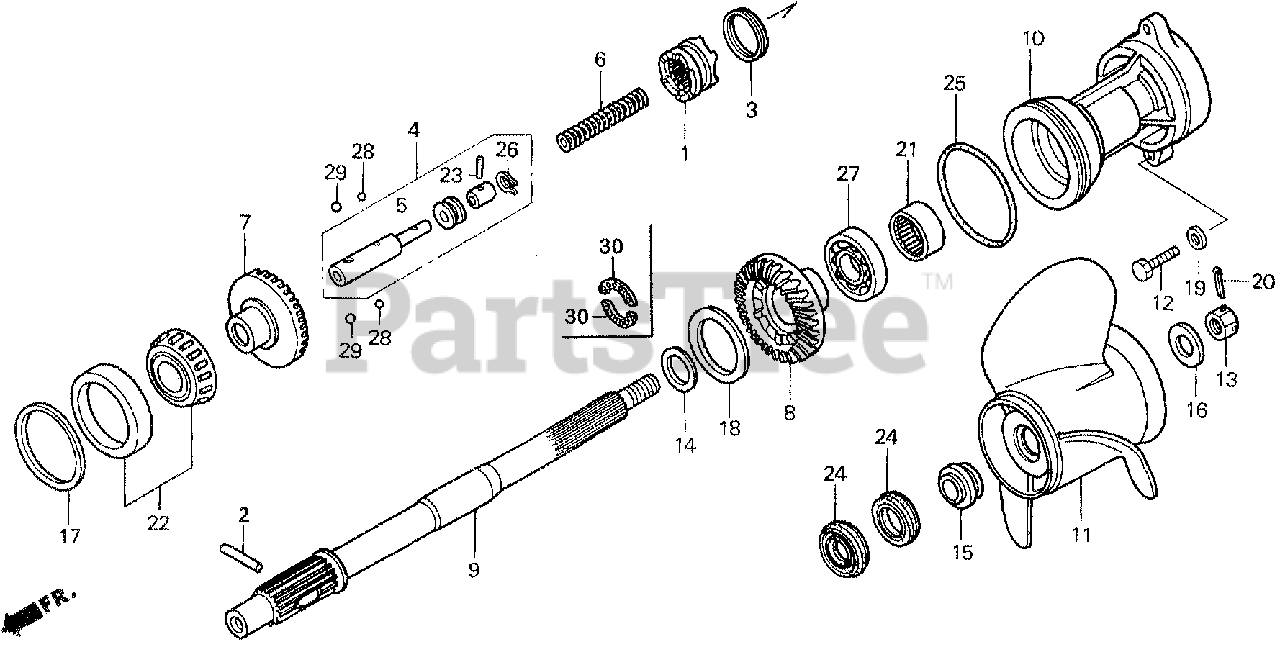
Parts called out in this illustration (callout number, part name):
1	SHIFTER, CLUTCH
2	PIN, SHIFTER (8X47)
3	RING, CROSS PIN
4	SLIDER, SHIFT
5	SLIDER, SHIFT
6	SPRING, SHIFT
7	GEAR, BEVEL (F)
8	GEAR, BEVEL (R)
9	SHAFT, PROPELLER
10	HOLDER, PROPELLER SHAFT *NH282MU* (OYSTER SILVER METALLIC-U)
11	PROPELLER, THREE-BLADE (13X19)
11	PROPELLER, THREE-BLADE (13X21)
11	PROPELLER, THREE-BLADE (14X11)
11	PROPELLER, THREE-BLADE
12	BOLT, HEX. (10X40)
13	NUT, CASTLE (18MM)
14	WASHER (31MM)
15	WASHER, PROPELLER THRUST
16	WASHER, PLAIN (18.5MM)
17	SHIM A, BEVEL (F)
17	SHIM B, BEVEL (F)
17	SHIM C, BEVEL (F)
17	SHIM D, BEVEL (F)
18	SHIM A, BEVEL GEAR (R)
18	SHIM B, BEVEL GEAR (R)
18	SHIM C, BEVEL GEAR (R)
18	SHIM D, BEVEL GEAR (R)
19	WASHER, PLAIN (10MM)
20	PIN, SPLIT (4.0)
21	BEARING, NEEDLE (30X37X26)
22	BEARING, TAPERED ROLLER (50X82X21.5)
23	ROLLER (3X12.5)
23	ROLLER (3X12.8)
24	SEAL, WATER (30X45X7)
25	O-RING (94X4.1)
26	CIRCLIP (OUTER) (14MM)
27	BEARING, RADIAL BALL (6208)
28	BALL, STEEL (#6) (3/16)
29	BALL, STEEL (#11) (11/32)
30	BEARING, BALL (28X38X3)
